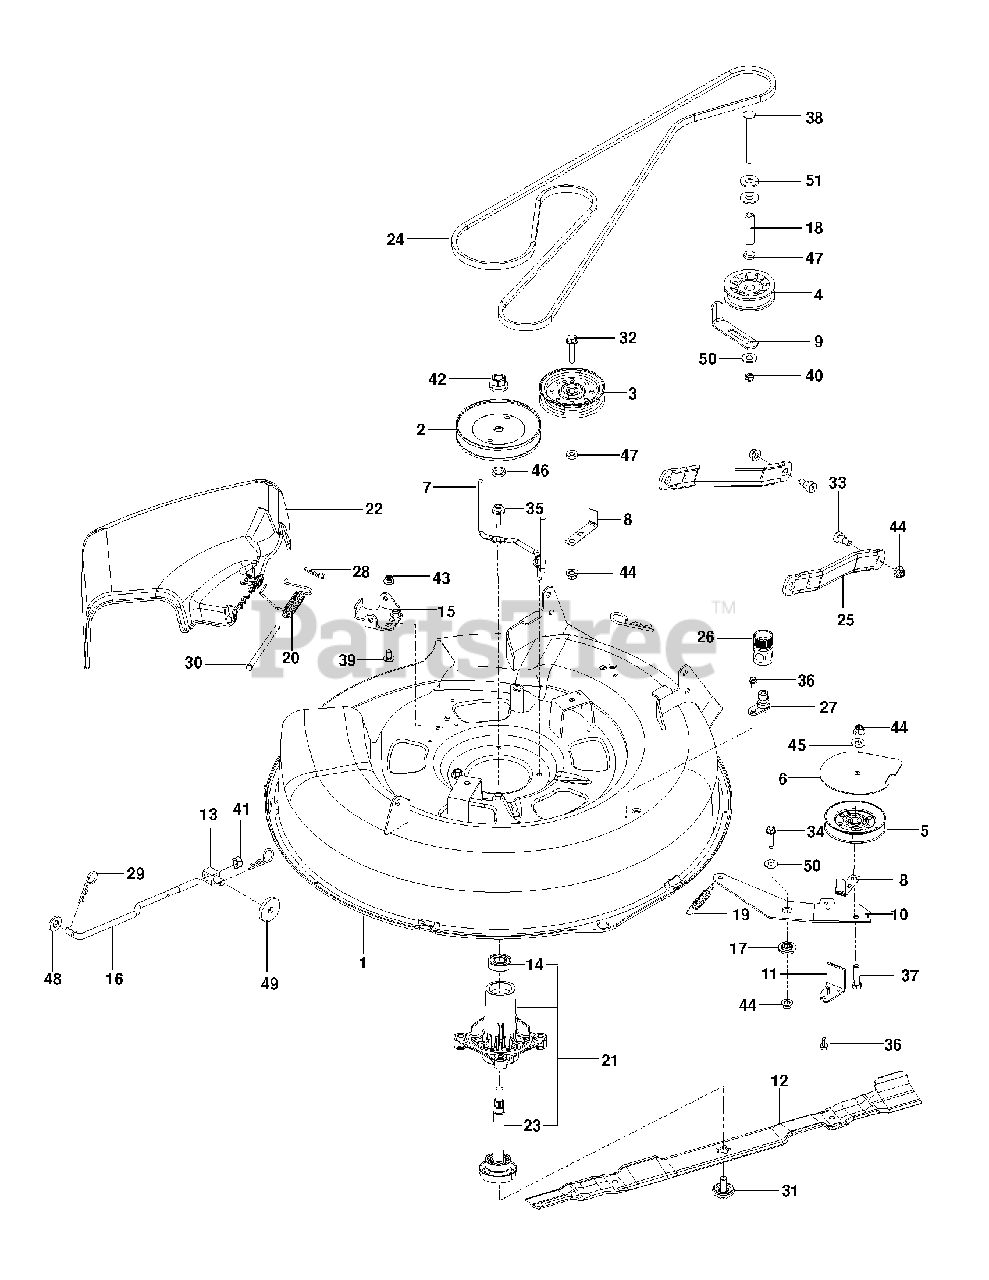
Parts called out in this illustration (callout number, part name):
1	DECK W/DECALS, BLUE
2	PULLEY MANDREL 5.0"
3	PULLEY.IDLER.FLAT.46.PR.DR.
4	PULLEY, IDLER
6	COVER, PULLEY, BLACK
7	KEEPER, MANDREL BELT
9	GUIDE, BELT
12	BLADE.MOWER.BAGGING.30"
14	BEARING
15	BRKT.DEFLECTOR.38"2005+
17	SPACER.RETAINER
18	SPACER .39 ID X 2.25
21	MANDREL.ASM.SUB-NON.GR
22	SHIELD.DEFLECT.MWR.30S.BLACK
23	SHAFT.ASM.MDRL.N/GREASE.38
25	ARM.SUSPENSION.MOWER
26	COUPLING.QUICK CONNECT
27	PORT.WASHOUT
28	HAIRPIN #2
29	HAIRPIN #4
30	PIN-CLEVIS 5/16 DIA X 5.19 ZD
31	BOLT.WASHER.ASM.7/16-2
31	SCREW- 1/4-20 X 5/8
32	BLT 3/8-16X1-3/4 WHIZLK ZN SP
33	SB 3/8-16 X 3/8 SKT HD ZD
35	SCREW, WASHER HEAD
38	RHSNB 3/8-16 X 4 GR5 ZD
39	BOLT
41	NUT, 7/16-20 HEX NYLOC ZC
42	NUT.FLANGE.LOCK.TOP
43	5/16-18 NYLOC FLANGE NUT
44	NUT 3/8-16 HEX FLG NYLOC ZD
45	WASHER
46	WASHER.SPACER.MANDREL
47	WASHER 3/8 X 3/4 X .187 TK
49	SPINDLE WASHER
51	WASHER 7/16 FLAT ZD
